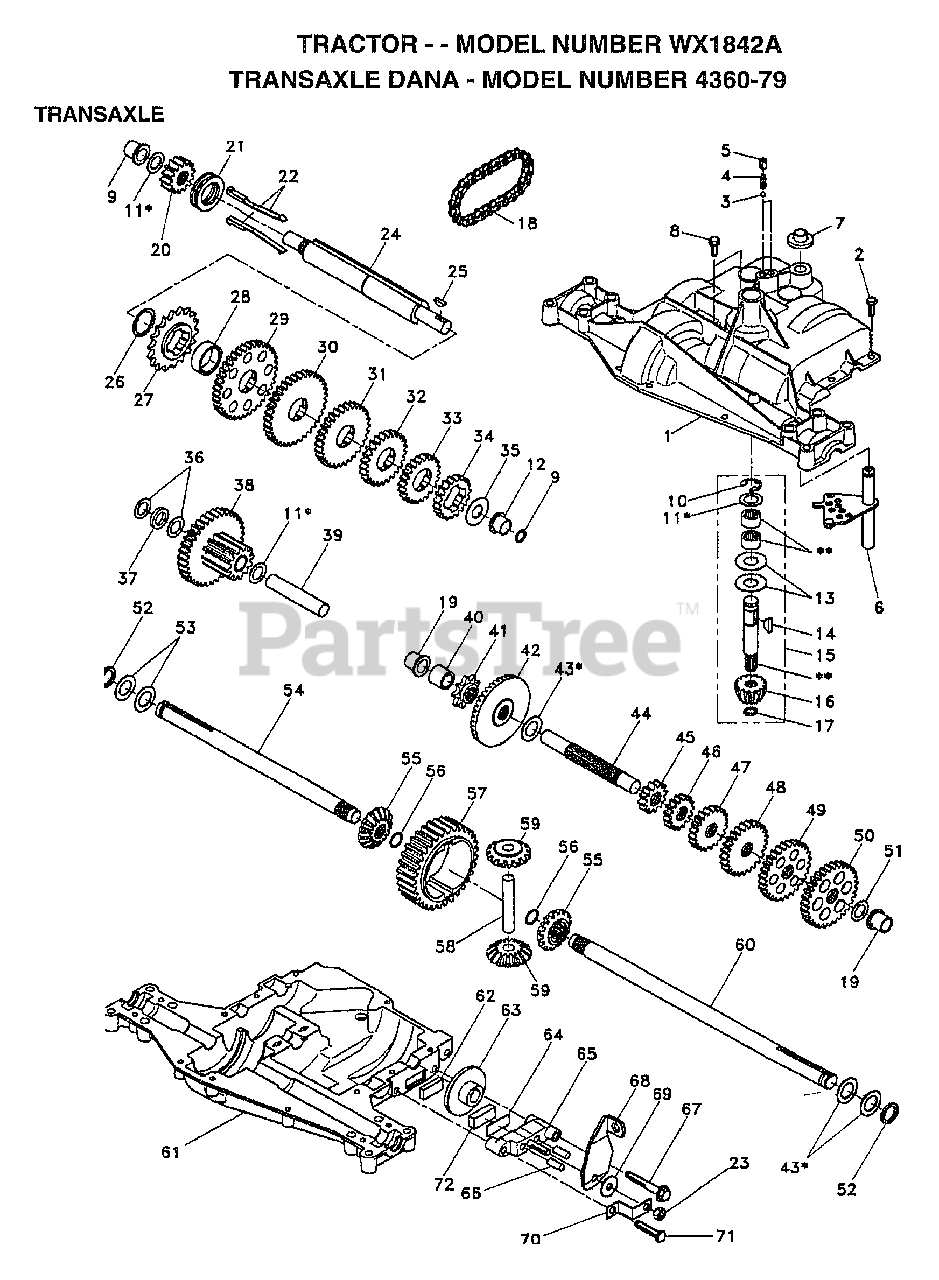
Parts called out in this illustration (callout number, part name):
1	HOUSING UPPER TRN
4	"SPRING, DETENT LT"
5	"SCREW, SET LT"
6	KIT SHIFTER ASM
7	SHIFTER BOOT
8	SCREW TAP W/SEAL
9	SQUARE RING
11	ASM KIT SHIM 4689
12	BEARING FLAN-DANA
13	WASHER T
14	KEY WOODRUFF-DANA
15	AS KIT INPUT SHFT
16	PINION 14T T
17	"RING,RETAINING LT"
18	"CHAIN,24 PTCH LT"
19	BEARING.FLNG.5510
20	GEAR SPUR 14 TTH
21	COLLAR CLUTCH
22	ASM KIT CLTCH KEY
23	NUT.LOCK.5/16-24
24	SHAFT INTERM DANA
25	WOODRUFF KEY
26	"RING,RETAINING LT"
27	SPROCKET 18T T
28	SPACER YT
29	GEAR SPUR 37 TTH
30	GEAR SPUR 35 TTH
32	GEAR 25T LT
33	GEAR SPUR 22 TT
34	SPUR GEAR 19T
35	"WASHER, PLAIN LT"
36	WASHER 025
37	SPACER
38	ASSM GEAR COMB
39	SHAFT IDLER
40	SPACER T
41	SPROCKET 9T LT
43	ASM KIT SHIM
44	SHAFT T
45	GEAR SPUR 12 TTH
46	GEAR SPUR 15 TTH
48	"GEAR, SPUR 25T LT"
49	GEAR 28T T
50	"GEAR, SPUR 31T LT"
51	WASHER 060
52	NEOPRENE WASHER
53	WASHER 031
55	GEAR 15T T
56	"RING,RETAINING LT"
58	SHAFT T
59	GEAR 1ST T
61	HOUSING LOWER TNS
62	PUCK T
63	BRAKE DISC. T
64	SPACER LT
66	PIN T
69	WASHER LT
71	"SCREW, TAPPING LT"
72	PUCK T
